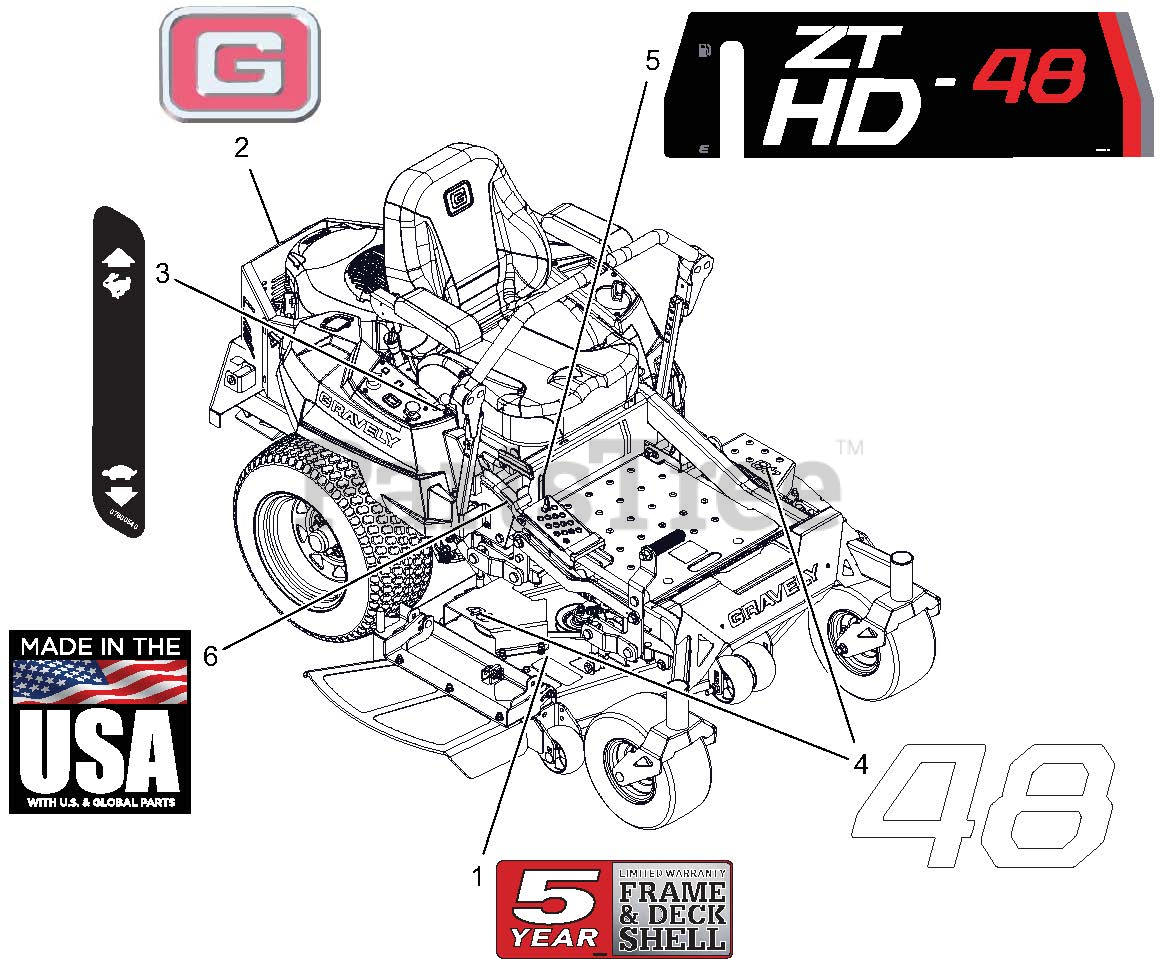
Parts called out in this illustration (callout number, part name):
1	DECAL,DECK WARRANTY-FAB GRVLY
2	DECAL, GRAVELY BRAND
3	DECAL, DASH DECAL
4	DECAL, 48"
5	DECAL - 48HD
6	DECAL, MADE IN USA
